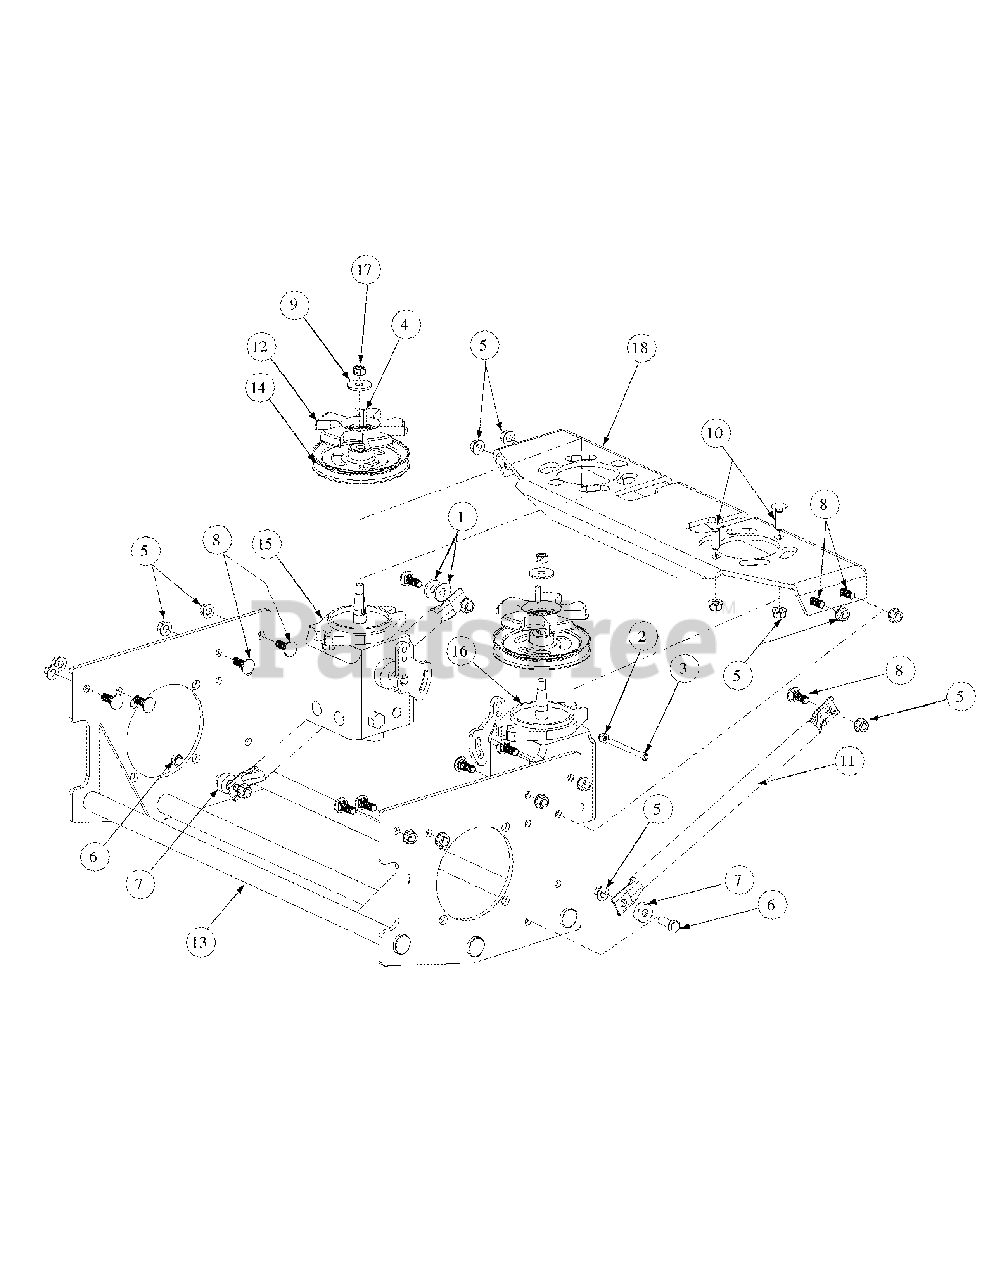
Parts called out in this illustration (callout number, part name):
1	Washer lock 3/8 zinc
2	Lock Nut, Nylon Insert, 1/4-20
3	Socket Head Cap Screw, 1/4-20 x 2-1/2
4	Key, 3/16" x 7/8"
5	Flange Lock Hex Nut, 3/8-16
6	Hex Cap Screw, 2/8 -16 x 1.25
7	Spacer, .406 ID x 1.00 OD x .38
8	Carriage Bolt, 3/8-16 x 1
9	Flat Washer, .411 x 1.25 x .100
10	Carriage Screw, 3/8-16 x 1.25
12	Hydro Pulley Fan
13	Hydro Motor Frame Assembly
14	Hydro Pulley Pump
15	Hydro Pump, LH
16	Hydro Pump, RH
17	Hex Nut, 3/8-24
18	Hydro Pump Mounting Weldment
